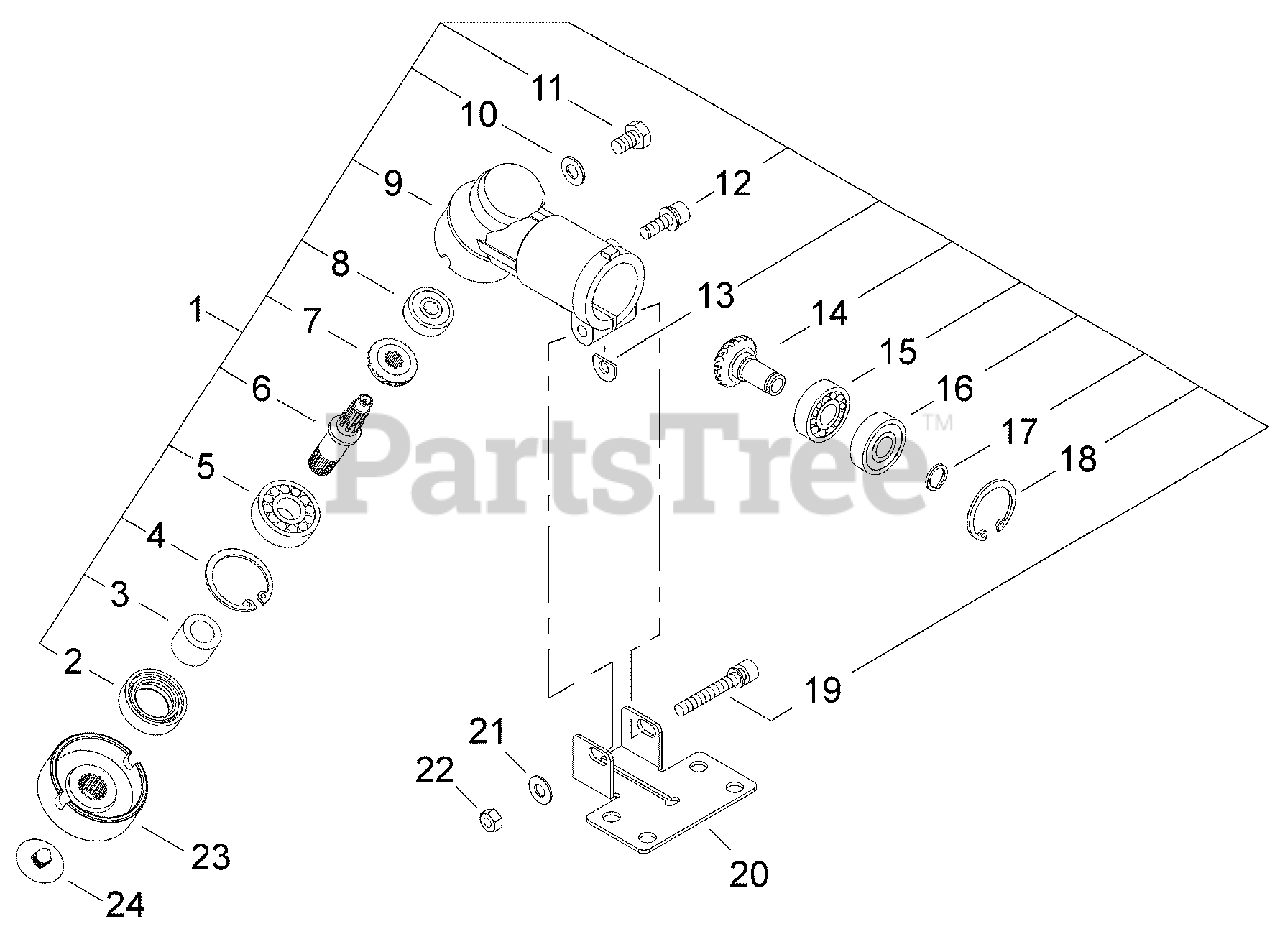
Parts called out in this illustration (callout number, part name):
1	GEAR CASE ASSY
2	SEAL, OIL
3	SPACER
4	RING, SNAP Ø26
5	BEARING, BALL 6000
6	SHAFT, GEAR
7	GEAR, BEVEL
8	BEARING, BALL 626 DDU
9	HOUSING, GEAR CASE
10	WASHER
11	BOLT M6×10
12	BOLT M5×16
13	D-WASHER
14	GEAR, PINION
15	BEARING, BALL 608
16	BEARING, BALL 608ZZ
17	RING, SNAP
18	RING, SNAP Ø22
19	BOLT M5×35
20	PLATE, SHIELD MOUNTING
21	WASHER 5 MM
22	NUT M5
23	HOLDER
24	CLIP
